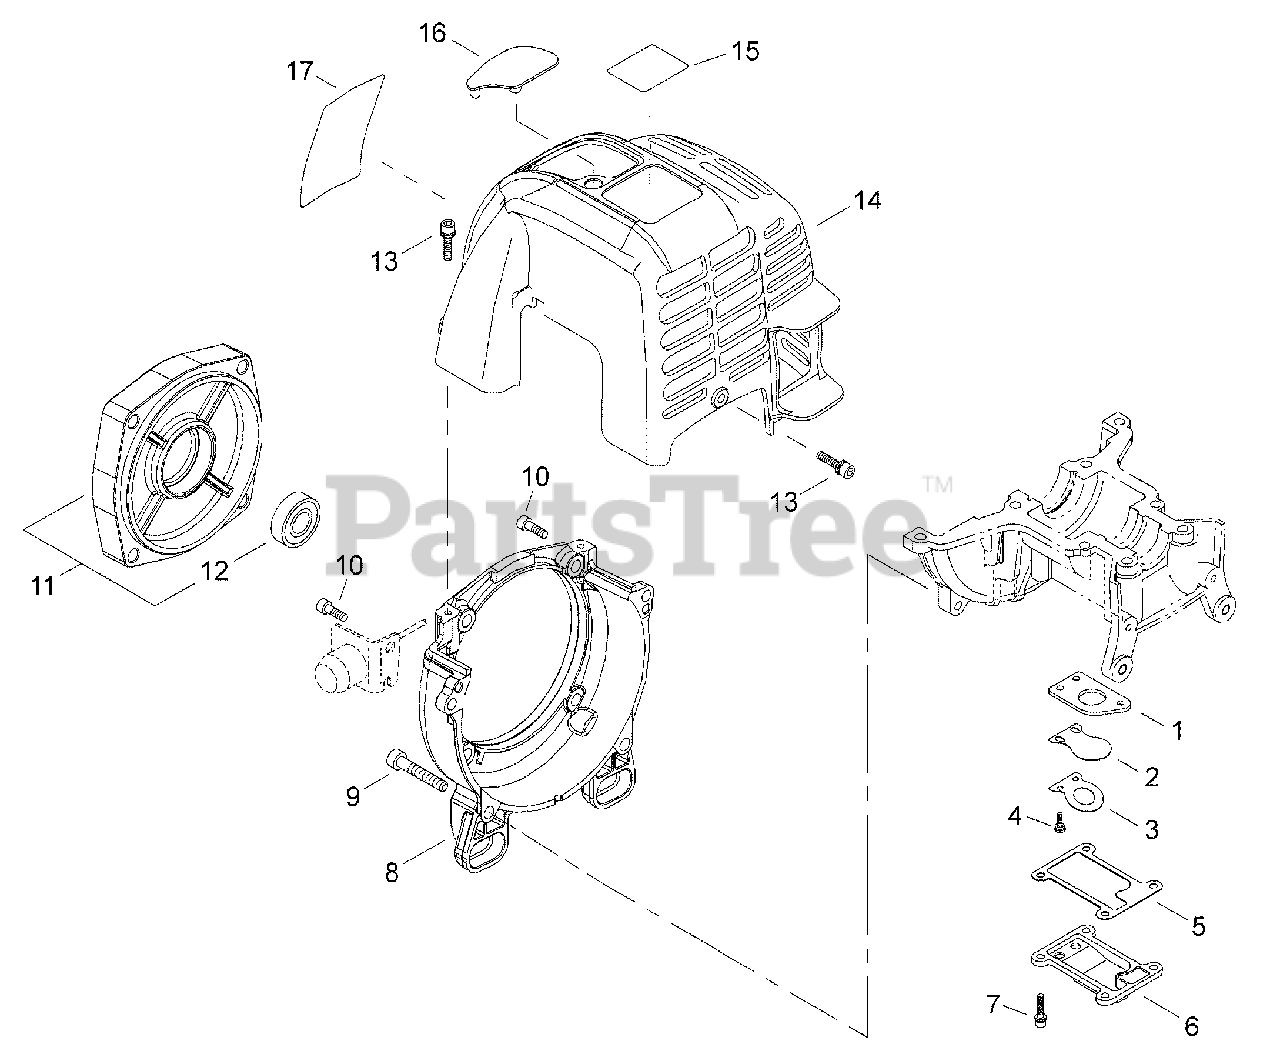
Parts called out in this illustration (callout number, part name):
1	PLATE, REED BACKING
2	VALVE, REED
3	STOP, REED VALVE
4	SCREW M3×10
5	GASKET, REED VALVE
6	COVER, REED VALVE
7	BOLT M4×14
8	COVER, FAN
9	BOLT 5×30
10	BOLT 5×16
11	ADAPTOR SET, PUMP
12	BEARING, BALL 6002
13	BOLT M4×14
14	COVER, ENGINE
15	LABEL, E4 W4000
16	COVER, SPARK PLUG
17	LABEL, SWISHER E4
